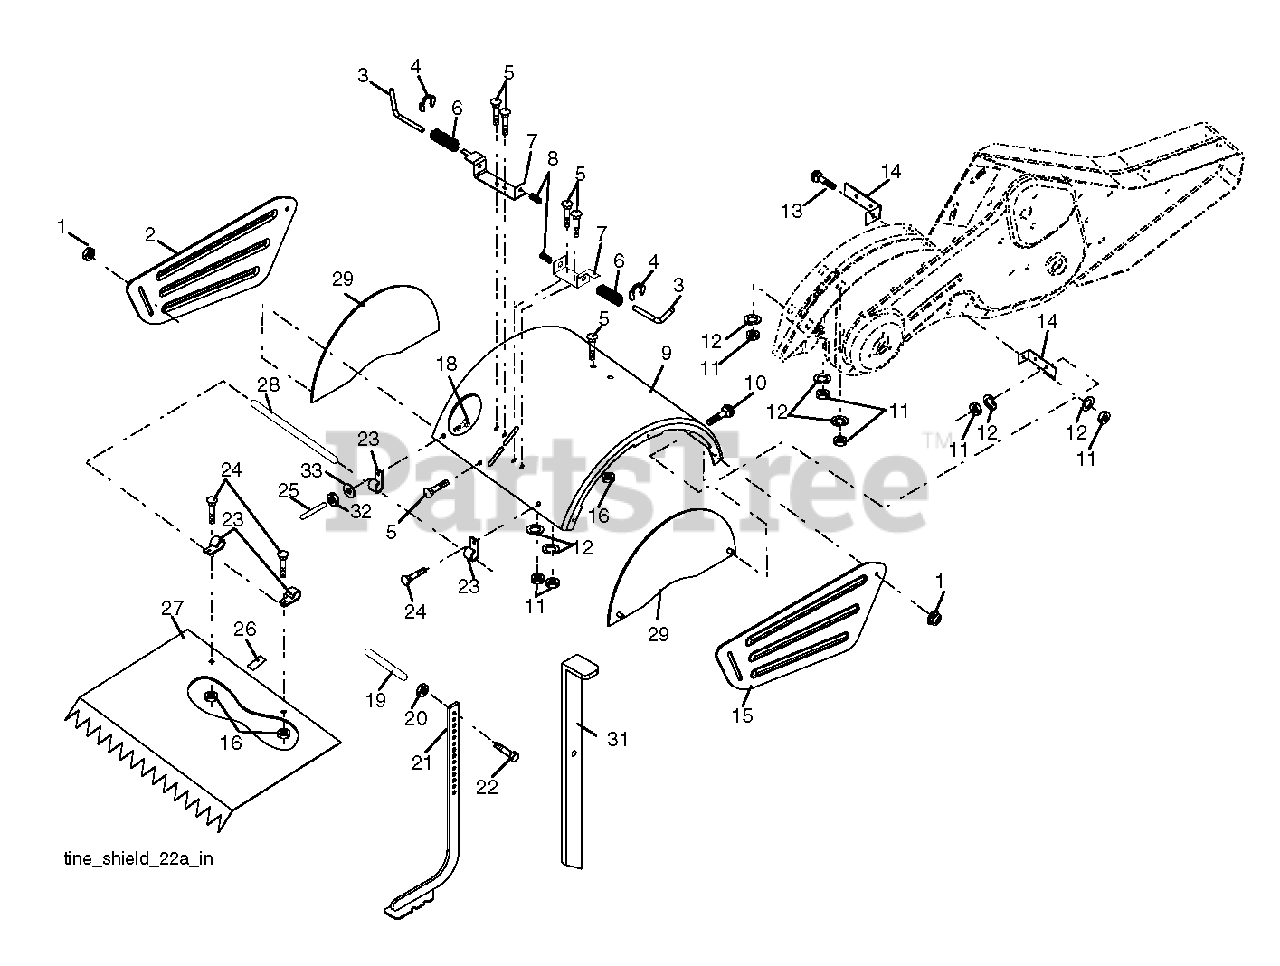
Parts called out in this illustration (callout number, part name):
1	NUT LOCK HEX FLANGE 5/16-18
2	SHIELD
3	STAKE PIN TI
4	RING, KLIP
5	BOLT, RDHD SQNK 5/16-18 X 3/4
7	BRACKET.LATCH.STAKE.3.20.BLACK
8	SPRING CRT
9	SHIELD.PNT.TINE.17"M
12	LOCKWASHER
13	BOLT.CARRIAGE.5/16-18
14	BRACKET.TINE.SHIELD.TILLER
15	SIDE SHIELD RH
16	NUT T
20	NUT.HEX.3/8-16UNC
21	STAKE.DEPTH.16.CRT.BLACK
22	BOLT.375-16
26	PAD IDLER TI
27	SHIELD LEVELING
28	PIN.HINGE.TILLER
29	SHIELD.ASM.SIDE.ORANGE.(OLD)
31	STAKE.PNT.DEPTH.DRAG
32	NUT
33	LOCKWASHER
